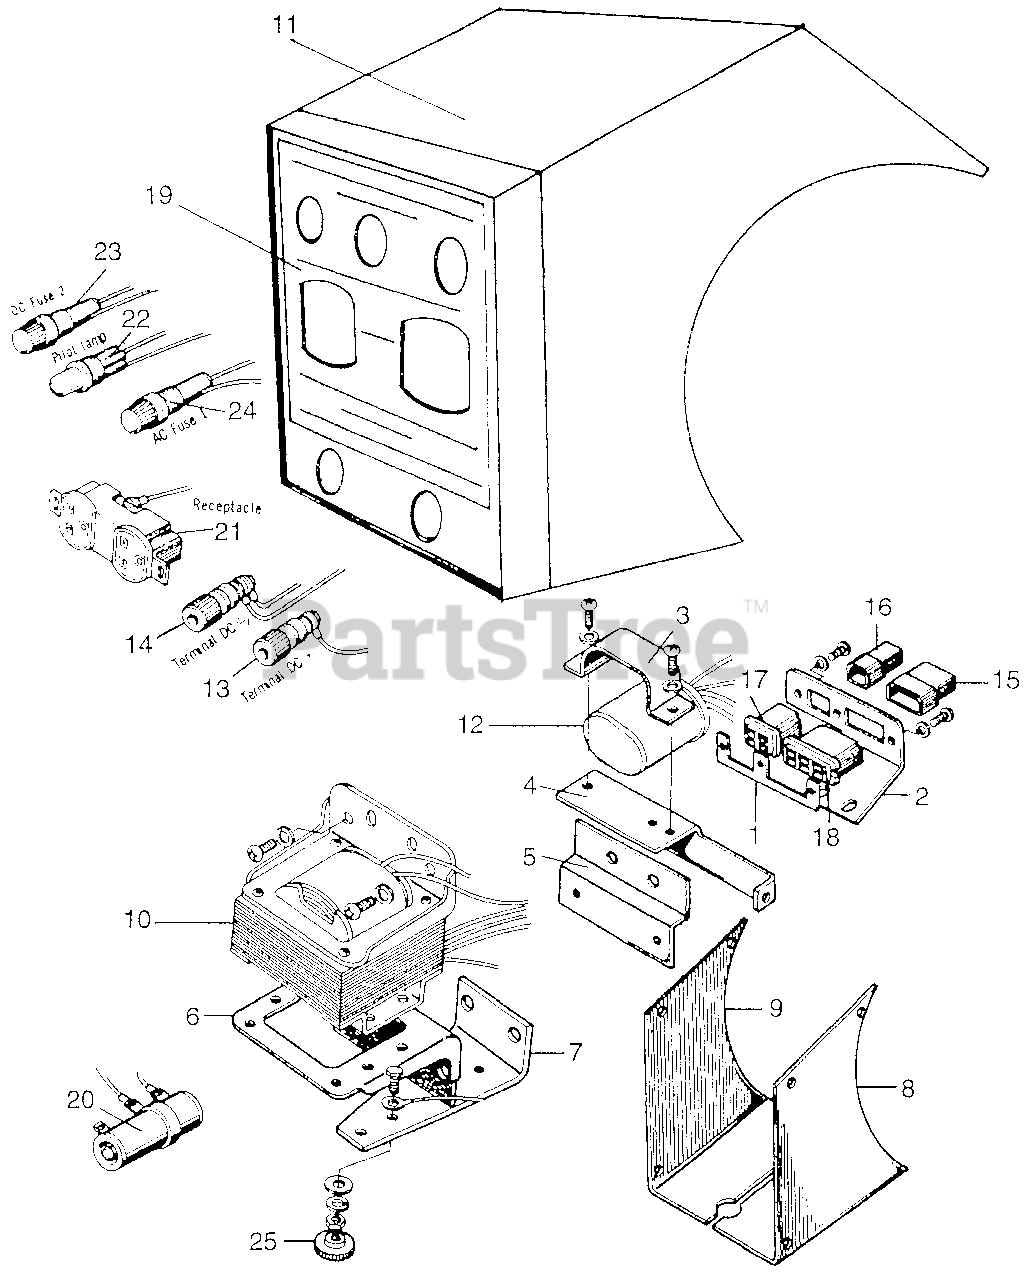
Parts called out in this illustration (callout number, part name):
1	WASHER, CONNECTOR
2	STAY, CONNECTOR
3	BAND, CONDENSER
4	STAY, CONDENSER
5	STAY A, TRANSFORMER
6	STAY B, TRANSFORMER
7	STAY, RESISTOR
8	COVER B, CONTROL (LOWER) *NH31* (MCKINLEY WHITE)
9	COVER A, CONTROL (LOWER) *NH31* (MCKINLEY WHITE)
10	TRANSFORMER
11	COVER, CONTROL (UPPER) *NH31* (MCKINLEY WHITE)
13	TERMINAL ASSY., GROUND (NOT AVAILABLE)
14	TERMINAL ASSY., B (NOT AVAILABLE)
15	CONNECTOR (6PCR)
15	CONNECTOR (6PCR) (NOT AVAILABLE)
16	CONNECTOR (4PCR)
16	CONNECTOR (4PCR) (NOT AVAILABLE)
17	CONNECTOR (4PCT)
17	CONNECTOR (4PCR) (NOT AVAILABLE)
18	CONNECTOR (6PCT)
18	CONNECTOR (6PCT) (NOT AVAILABLE)
19	PLATE, CONTROL (NOT AVAILABLE)
20	RESISTOR SET
21	RECEPTACLE (15A-125V)
22	BULB (24V2W)
22	SOCKET ASSY., PILOT LAMP
23	FUSE (10A)
23	HOLDER ASSY., FUSE (NOT AVAILABLE)
24	HOLDER FUSE (NOT AVAILABLE)
24	FUSE A (15A)
25	NUT, SPECIAL (6MM)
